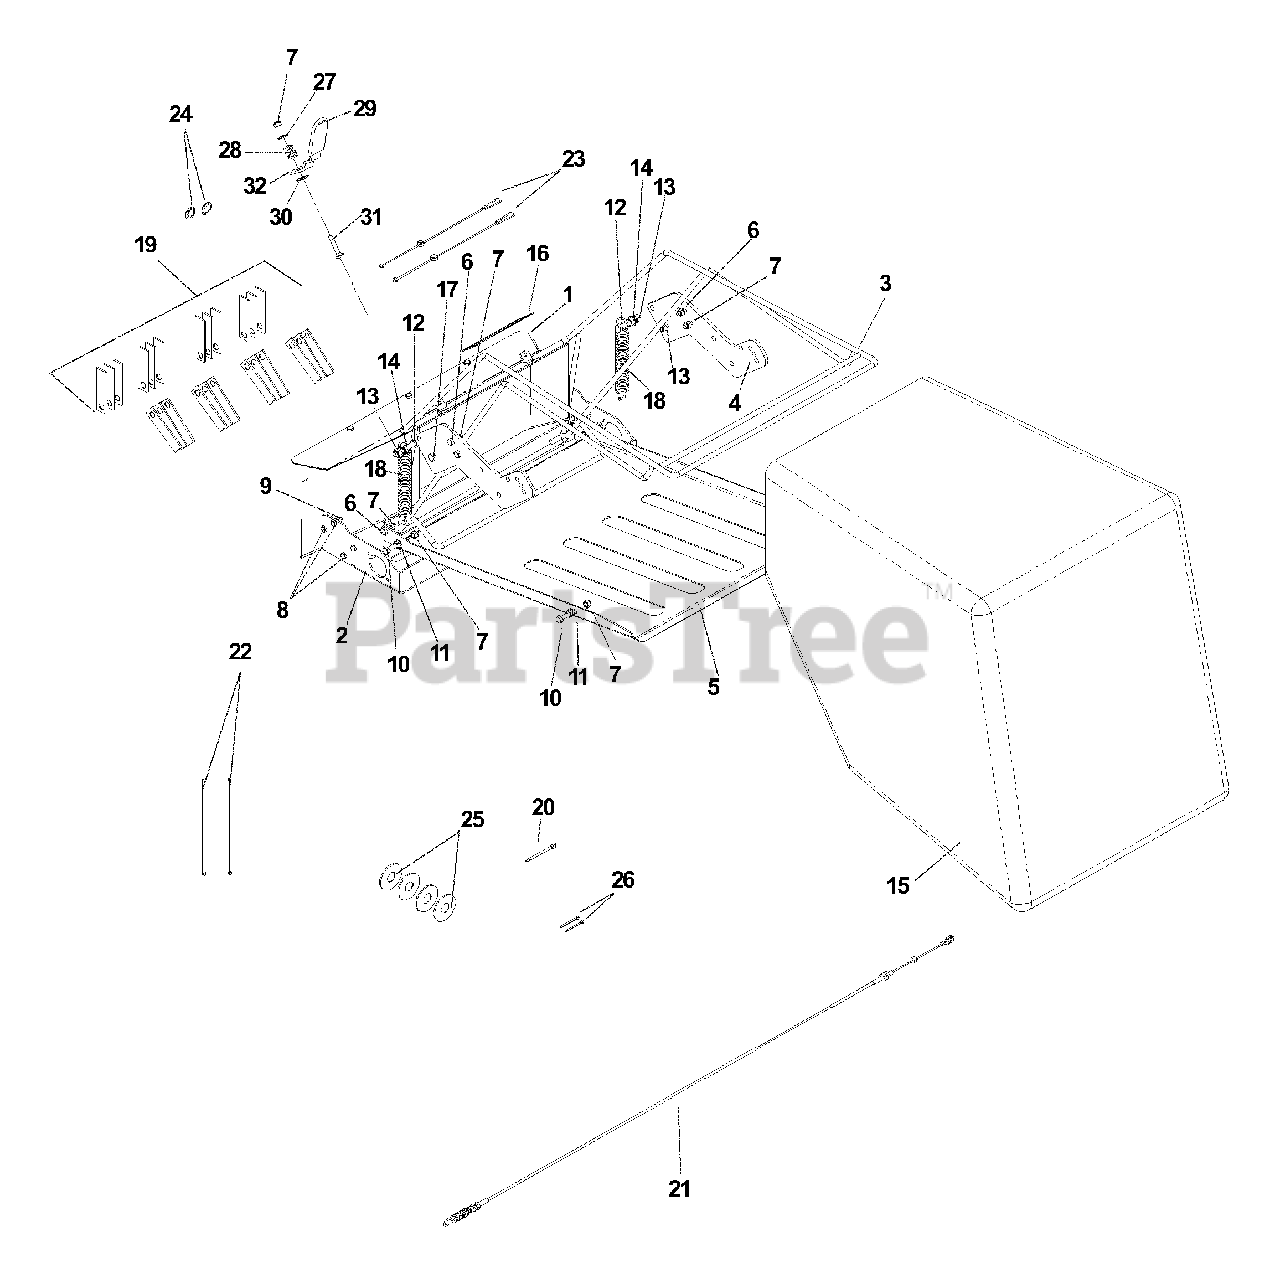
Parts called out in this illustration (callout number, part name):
1	CHUTE
3	BAG FRAME, BLACK
5	SAFETY DOOR
6	SCREW, 5/16 X 1
7	NUT, 5/16, NYLOC
8	SCREW, 1/4 X 3/4
9	NUT, 1/4, NYLOC
10	SCREW, 5/16 X 1 3/4
11	NUT, 5/16, SERRATED WASHER
12	SCREW, 3/8 X 2
13	NUT, 3/8, NYLOC
14	NUT, 3/8, SERRATED WASHER
16	DECAL, WARNING
17	SCREW, 3/8 X 1
18	SPRING, BAGGER
19	BLADE SET (56)
20	COTTER PIN 1/8 X 1 1/2
21	CABLE, BAGGER
22	WIRE TIE
23	LANYARD
24	RETAINING RING
25	WASHER, 5/8, SAE
26	COTTER PIN, 3/32 X 3/4
27	WASHER, 5/16
30	WASHER, 3/8
31	RHSNB, 5/16-18 X 1 3/4
